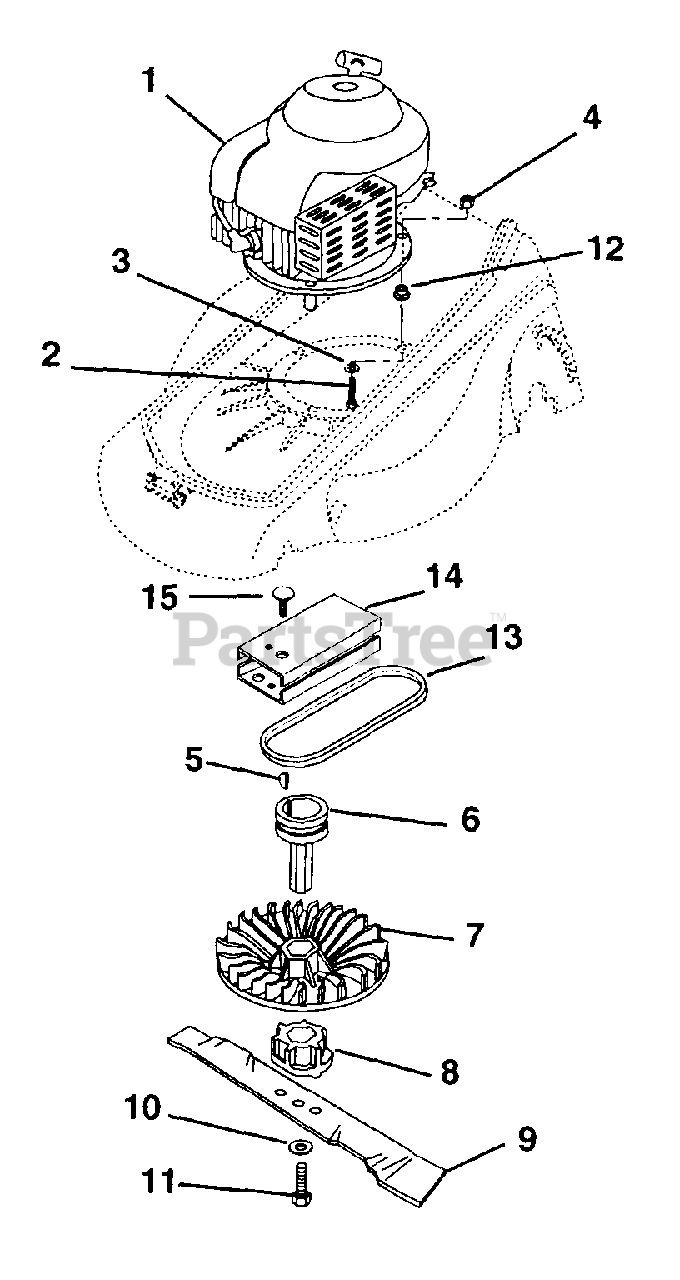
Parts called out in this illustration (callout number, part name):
1	ENGINE, B&S SPRINT 4HP F.S.L.S
2	BOLT, M8X50 GRD 8
3	WASHER, ENGINE MOUNT
4	NUT, LK M8
5	KEY-WDRF 4X6.5MM
6	PULLEY, TRANSMISSION DRIVE
7	FAN, COOLING
8	ADAPTER, BLADE
9	BLADE, MULCHING
10	WASHER, BELLEVILLE 10.5X23X2.5
11	BOLT, .375X24X2
12	BUSHING, ENGINE MOUNT
13	BELT, V TRANMSN DRV SPZ-787 4L
14	COVER, V BELT
15	PIN, V BELT COVER ANCHOR
